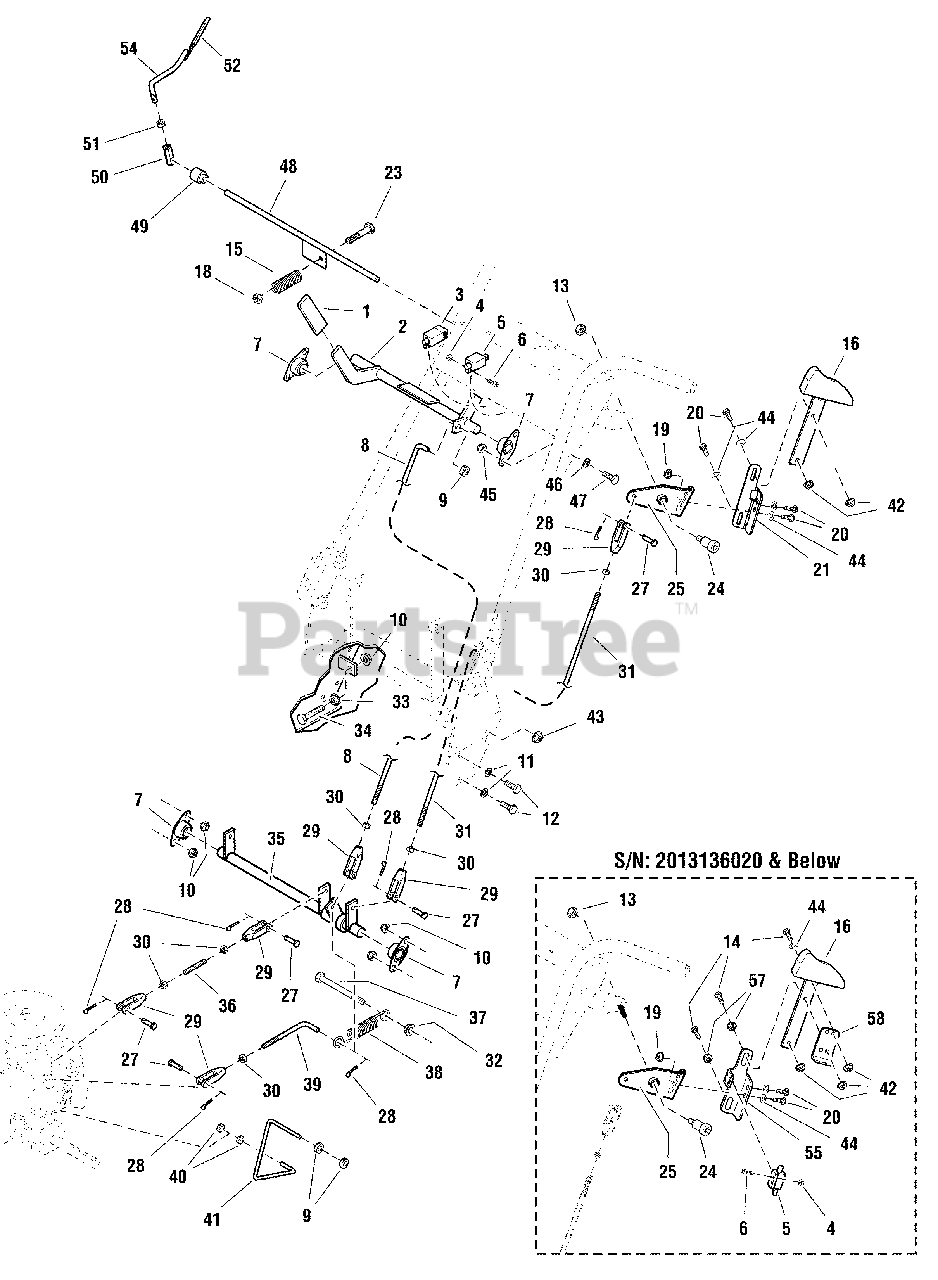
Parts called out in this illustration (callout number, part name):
1	GRIP, FOAM, 1/4" X 1
2	WELD, BRAKE CONTROL
3	SWITCH, Plunger, NO/NO
4	NUT, #10-24 HEX
5	SWITCH, Plunger, NC
6	SCREW, #10-24 X 1/2" ROUND PHILLIPS
7	BEARING, BRONZE FLANGE, 3/4
8	ROD, PARKING BRAKE LINKAGE
9	COLLAR, 5/16" SET
10	NUT, 5/16-18 HEX NYLOCK FLANGE
11	WASHER, 5/16" SAE
12	BOLT, 5/16-18 X 3/4 GD5
13	NUT, 3/8-16 HEX SIDE LOCK
14	BOLT, 1/4-20 X 1" GD5 CZ
15	SPACER, SLIDE
16	HANDLE, RUBBER HYDROCUT - LH
18	ACTUATOR, SWITCH
19	NUT, 1/4-20 HEX SERR. FLANGE
20	BOLT, 1/4-20 X 3/4" GD5 YZ
21	MOUNT, MOTION CONTROLS - LH
23	BOLT, 1/4-20 X 5/8" GD5 YZ
24	BOLT, 3/8-16 X 1.0", 1/2" SHOULDER
25	WELD, ARM CONTROL, LH
27	PIN, CLEVIS, 5/16" X 1
28	PIN, 3/32 X 0.750, COT, ZINC/CLEAR
29	CLEVIS, 5/16-24, PLASTIC
30	NUT, 5/16-24 HEX
31	ROD, THUMB CONTROL LINKAGE
32	NUT, 3/8-16 HEX SERRATED FLANGE
33	NUT, 5/16-18 HEX SERRATED FLANGE (LARGE)
34	BOLT, 5/16-18 X 1 1/2" FLANGE
35	WELD, CONTROL SHAFT
36	LINK, STUD
37	BOLT, 3/8-16 X 4" GD5 CZ
38	SPRING, EXT, 3.875 X .70 LOOP
39	LINK, PARKING BRAKE LOWER
40	COLLAR, 1/4" SET
41	LEVER, DUMP VALVE
42	NUT, 1/4-20 HEX NYLOCK FLANGE
43	NUT, 3/8-16 HEX NYLOCK FLANGE
44	WASHER, 1/4 SAE
45	NUT, 3/8"-16 HEX NYLOCK FLANGE
46	WASHER, 3/8 SAE
47	BOLT, 3/8-16 X 3/4" GD5 CZ
48	SWITCH ROD
49	SPACER, SHOULDER
50	ADJUSTER, LINKAGE
51	NUT, 3/8-16 HEX, YZ
52	GRIP, VINYL, 1/2" X 4"
53	ASSM, OPERATOR PRESENCE, LH - RED
54	ASSM, OPERATOR PRESENCE, RH - RED
54	OPERATOR PRESENCE HANDLE - RH
55	MOUNT, MOTION CONT, LH
57	SPACER, SLIDE
58	ACTUATOR, SWITCH
